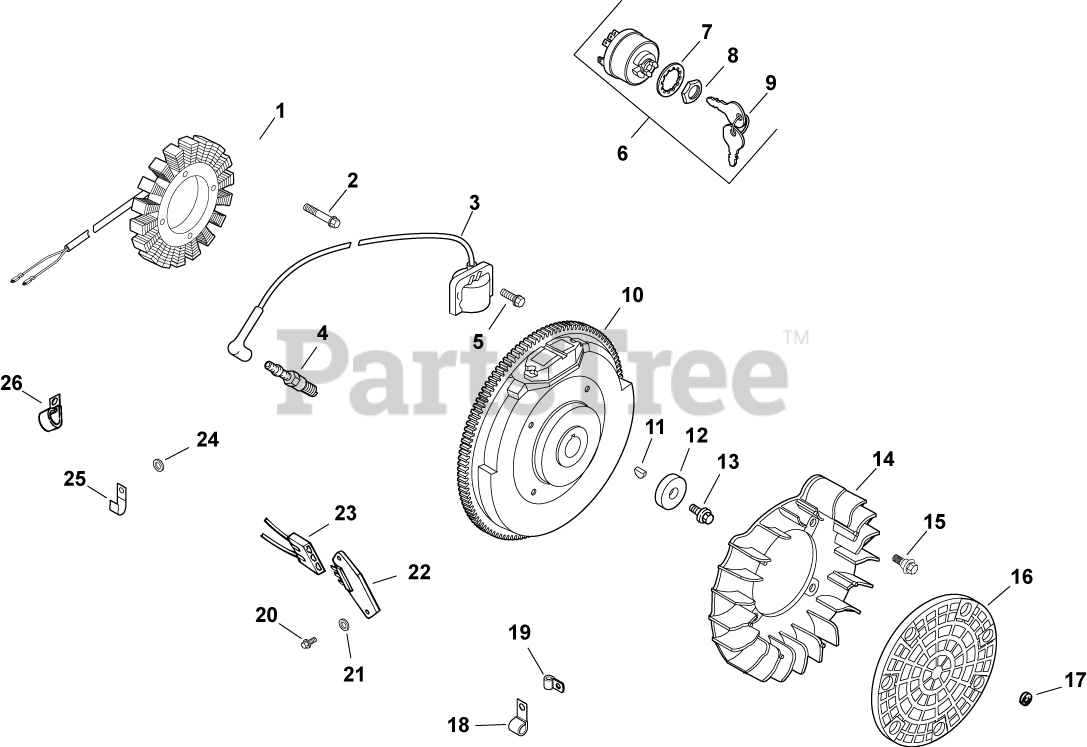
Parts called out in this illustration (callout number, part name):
1	KIT, 15 / 20 AMP STATOR
2	SCREW, M5X0.8X25 - (#25086402S)
3	KIT, MODULE IGNTN (CDI FIXED)
4	PLUG, SPARK (STD)
5	SCREW, FLG THD FRM M5X.8X20-(#25086399S)
6	SWITCH ASSY, KEY (KM)-USE 25 099 32-S
7	WASHER, INTERNAL TOOTH
8	NUT, KEY SWITCH
9	KEY, SET -USE 48 340 01-S
10	FLYWHEEL, PAINTED-USE 24 025 55-S
11	KEY, 3/16" X 5/8"
12	WASHER, FLAT 13/32"
13	SCREW, FLG M10X1.5X45 - (#25086361S)
14	FAN - USE (#24 157 11-S)
15	BOLT, SHOULDER
16	SCREEN, GRASS
18	CLIP, CABLE - USE 24 154 10-S
20	SCREW, PHL HD #11-16X7/8"
21	WASHER, FLAT 7/32"
22	REG/RECT-15 AMP (KM)-USE 41 403 10-S
23	CONNECTOR, BODY (KM)-USE 25 155 41-S
24	WASHER, FLAT 1/4" (O.D. 1/2")
25	CLIP, CABLE
26	CLIP, TUBE & WIRING (KM)
24176112-S	HARNESS, WIRING-USE 24 176 150-S
